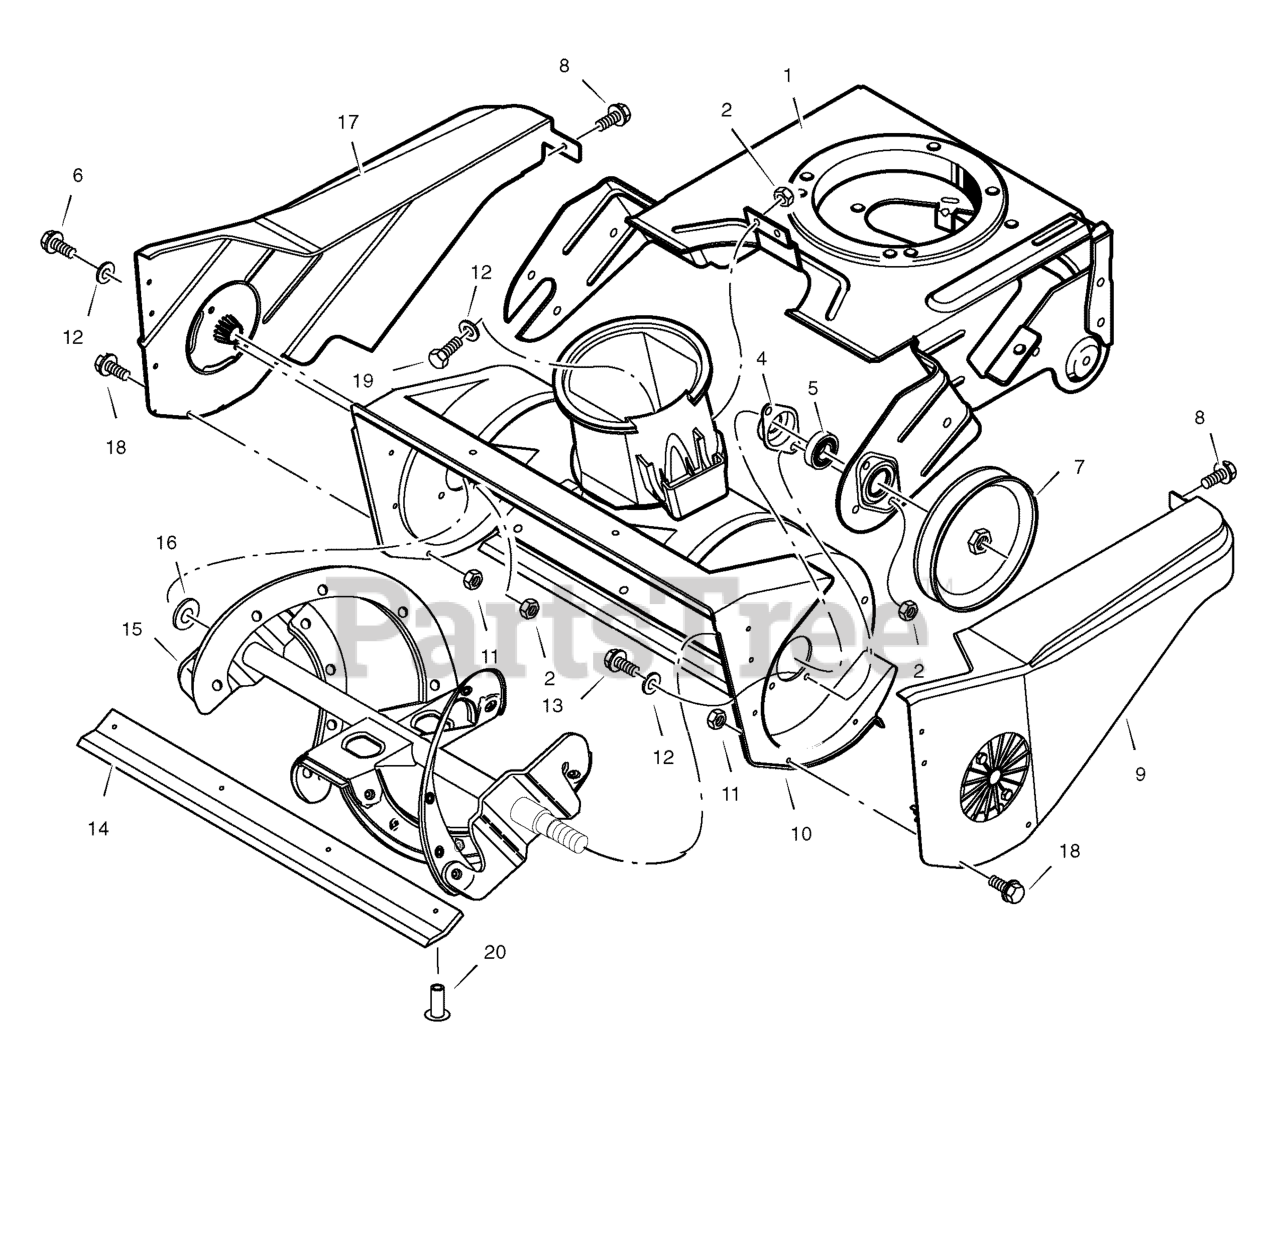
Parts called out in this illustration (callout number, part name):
1	Frame, Motor Box
4	Retainer, Bearing
5	Bearing
7	Pulley, Auger
9	Cover, Left Belt
10	Assembly, Auger Housing
11	Nut
12	Washer
14	Blade, Scraper
15	Auger Assembly
17	Cover, Right
